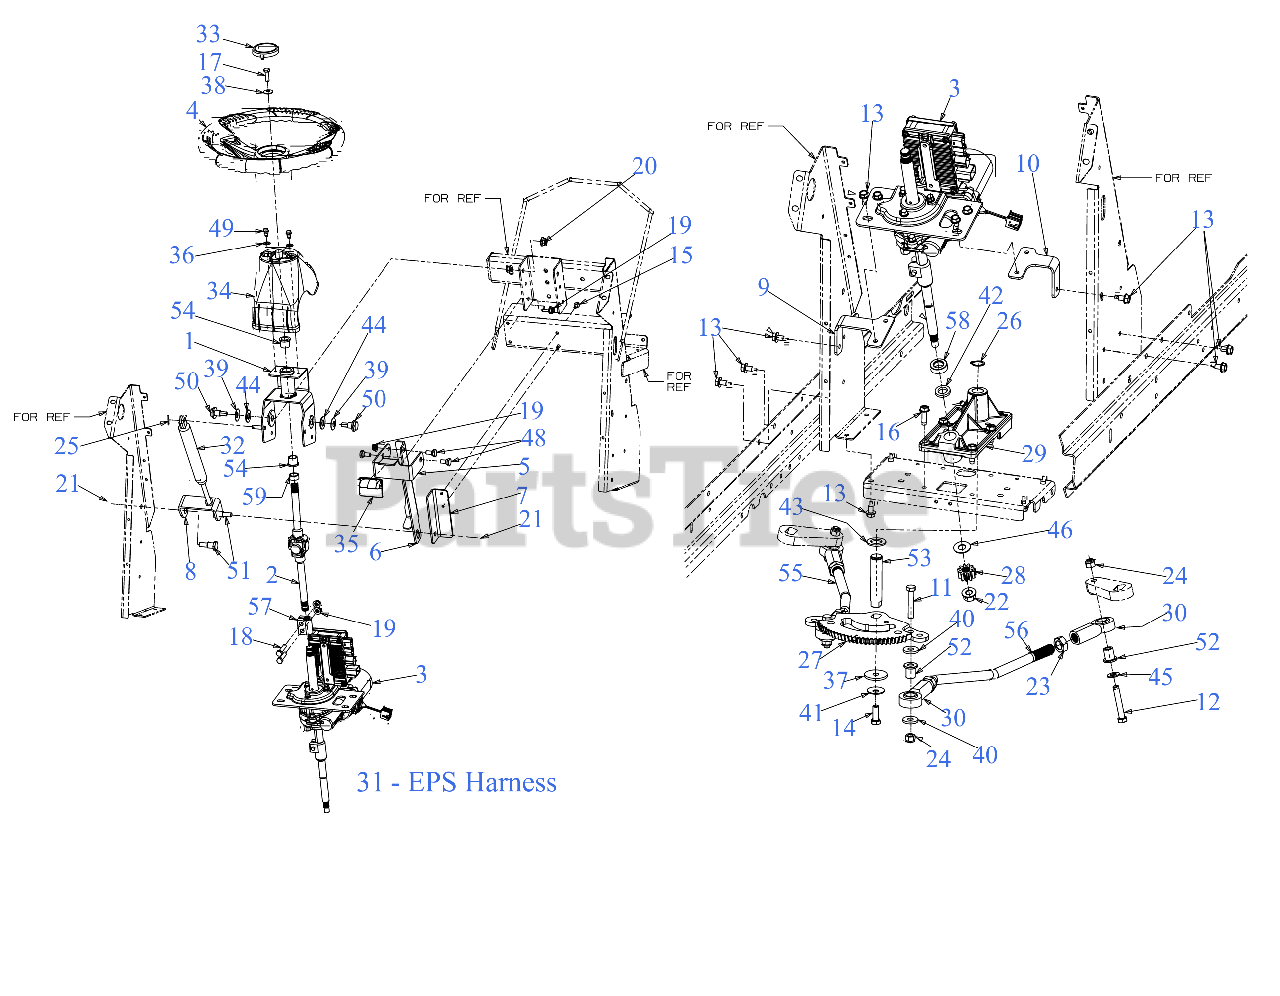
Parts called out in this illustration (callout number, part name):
2	UPPER STEERING SHAFT ASSEMBLY
3	EPS POWER STEERING TRANSMISSION
4	STEERING WHEEL
8	DAMPER CYLINDER PIVOT BRACKET
9	EPS MOUTING BRACKET (LH)
10	EPS MOUTING BRACKET (RH)
11	HEX SCREW 3/8-24 X2.00
12	HEX SCREW 3/8-24 x 2.25 GR5
13	SCREW 5/16-18 x .750
14	SCREW 3/8-24 x 1.00 GR5
15	SCREW 1/4-20 X.500
16	SCREW 5/16-18 x 1.00
17	SCREW 5/16-18 x 1.00 GR5
18	BOLT 5/16-18X1.375 GR5
19	FLANGE LOCK NUT 5/16-18
21	HEX LOCK NUT
22	FLANGE LOCK NUT
23	HEX JAM NUT 5/8-18
24	INSERT NUT 3/-24
25	COTTER PIN-3/32 DIA x .75
26	SNAP RING FOR .750 DIA SHAFT
27	STEERING GEAR SEGMENT
28	STEERING PINION GEAR
29	STEERING HOUSING ASSEMBLY
30	BALL JOINT ROD END
31	VOLT PROTECTOR HARNESS EPS PURPLE
32	DAMPER CYLINDER
33	STEERING WHEEL CAP
34	STEERING COLUMN
35	TILT WHEEL LEVER
36	FLAT WASHER .344 ID x .62 OD x .033
37	FLAT WASHER
38	BELL WASHER .337 X.867 x .057
39	BELL WASHER
40	FLAT WASHER .385 x 1.00 x .135
41	BELL WASHER .390x1.130x.062
42	FLAT WASHER .632X1.00X.16
43	SHIM WASHER .76X1.25X.10
44	FLAT WASHER
45	FLAT WASHER
46	FLAT WASHER
48	SHOULDER SCREW .437 DIA x .180
49	SHOULDER SCREW 1/4-20X.50 19"PSH
50	BOLT-SHLDR .49 DIA x .50
51	SHOULDER BOLT .50 DIA x .66
52	SHOULDER SPACER
53	STEERING SHAFT SEGMENT
54	FLANGE BEARING
55	STEERING DRAG LINK (LH)
56	STEERING DRAG LINK (RH)
57	STEERING SHAFT COUPLER
58	WIRE RING SPACER HUB
